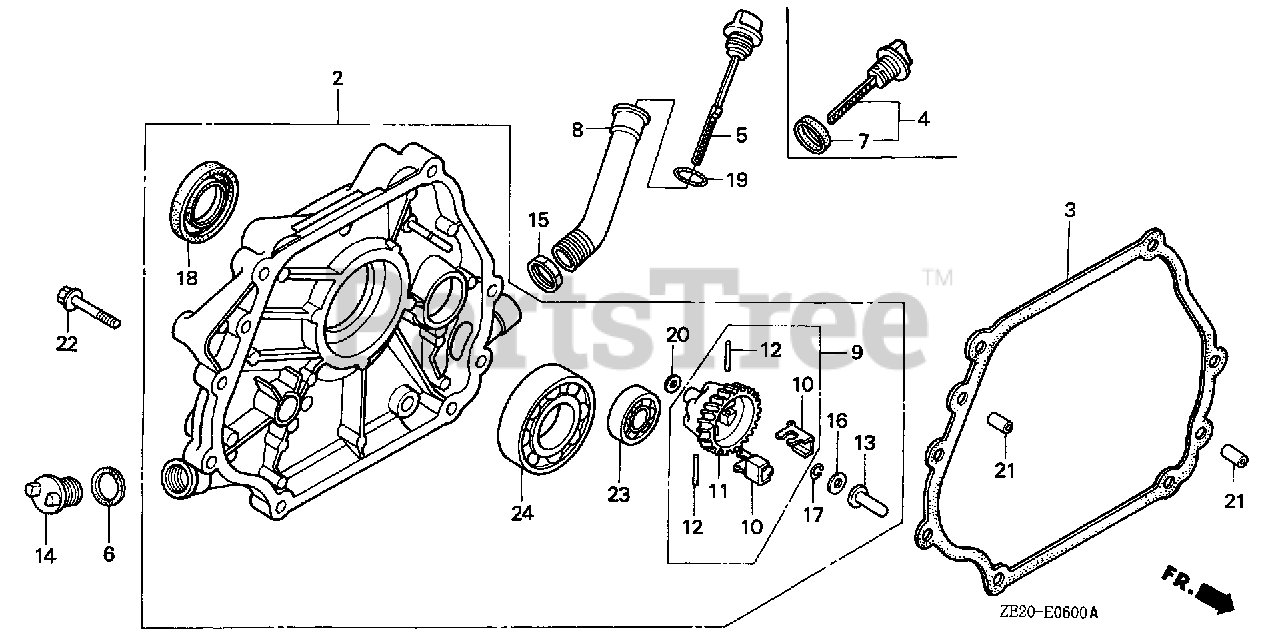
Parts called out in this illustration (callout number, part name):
2	COVER ASSY., CRANKCASE (NOT AVAILABLE)
2	COVER ASSY., CRANKCASE
3	GASKET, CASE COVER
5	CAP, OIL FILLER
6	GASKET, OIL FILLER CAP
8	PIPE, OIL FILLER
9	GOVERNOR ASSY. (NOT AVAILABLE)
9	GOVERNOR ASSY.
10	WEIGHT, GOVERNOR
11	HOLDER, GOVERNOR WEIGHT (NOT AVAILABLE)
11	HOLDER, GOVERNOR WEIGHT
12	PIN, GOVERNOR WEIGHT
13	SLIDER, GOVERNOR
14	CAP, OIL FILLER
14	CAP, OIL HOLE
15	NUT, OIL FILLER
16	WASHER (6X16)
17	CLIP, GOVERNOR HOLDER
18	OIL SEAL (30X46X8)
19	O-RING (16MM)
20	WASHER, PLAIN (6MM)
21	PIN, DOWEL (8X12)
21	PIN A, DOWEL (8X12)
22	BOLT, FLANGE (8X35)
23	BEARING, RADIAL BALL (6202)
24	BEARING, RADIAL BALL (6206)
